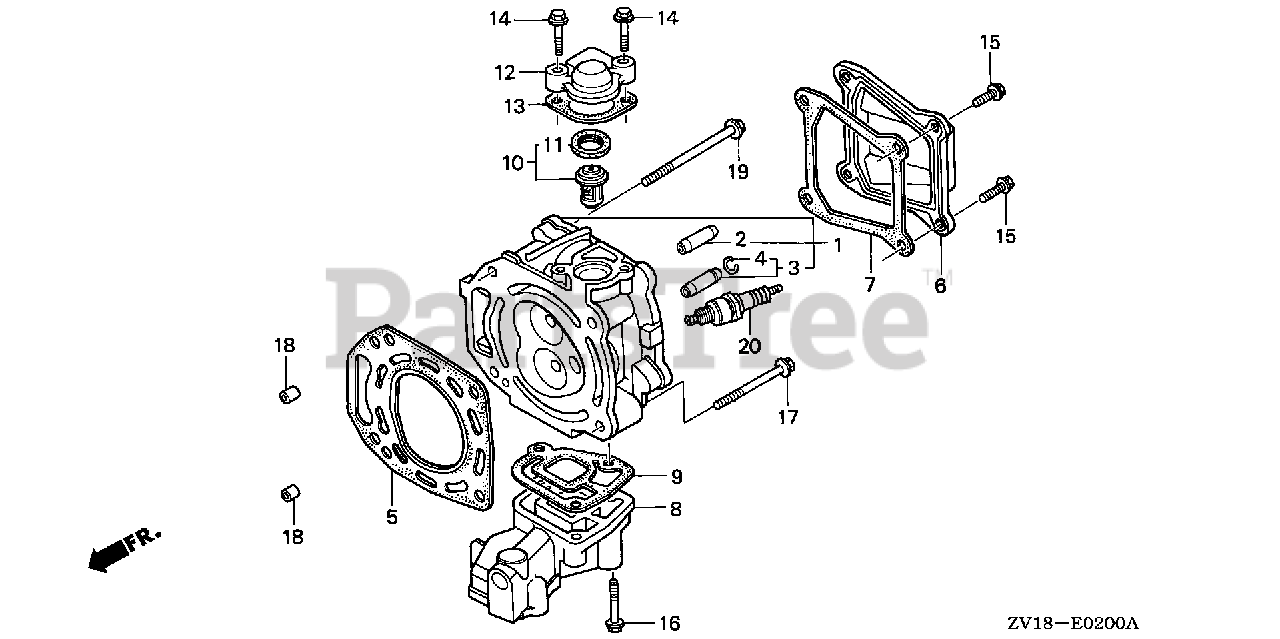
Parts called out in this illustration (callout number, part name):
1	CYLINDER HEAD *NH8* (DARK GRAY)
2	GUIDE, VALVE (OVER SIZE) Use from Engine SN 6324986.
3	GUIDE, EX. VALVE (OS)
4	CLIP, VALVE GUIDE Use from Engine SN 1231803.
5	GASKET, CYLINDER HEAD
6	COVER, HEAD
7	GASKET, CYLINDER HEAD COVER
8	MANIFOLD, EX. *NH8* (DARK GRAY)
9	GASKET, EX. MANIFOLD
10	THERMOSTAT ASSY.
11	RUBBER, THERMOSTAT
12	COVER, THERMOSTAT *NH8* (DARK GRAY)
13	GASKET, THERMOSTAT COVER
14	BOLT, FLANGE (6X23)
15	BOLT, FLANGE (6X12)
16	BOLT, FLANGE (6X32) (CT200)
17	BOLT, FLANGE (8X60)
18	PIN A, DOWEL (10X16)
19	BOLT, FLANGE (8X90)
20	SPARK PLUG (W16EPR-U)
20	SPARK PLUG (BPR5ES) (NGK)
